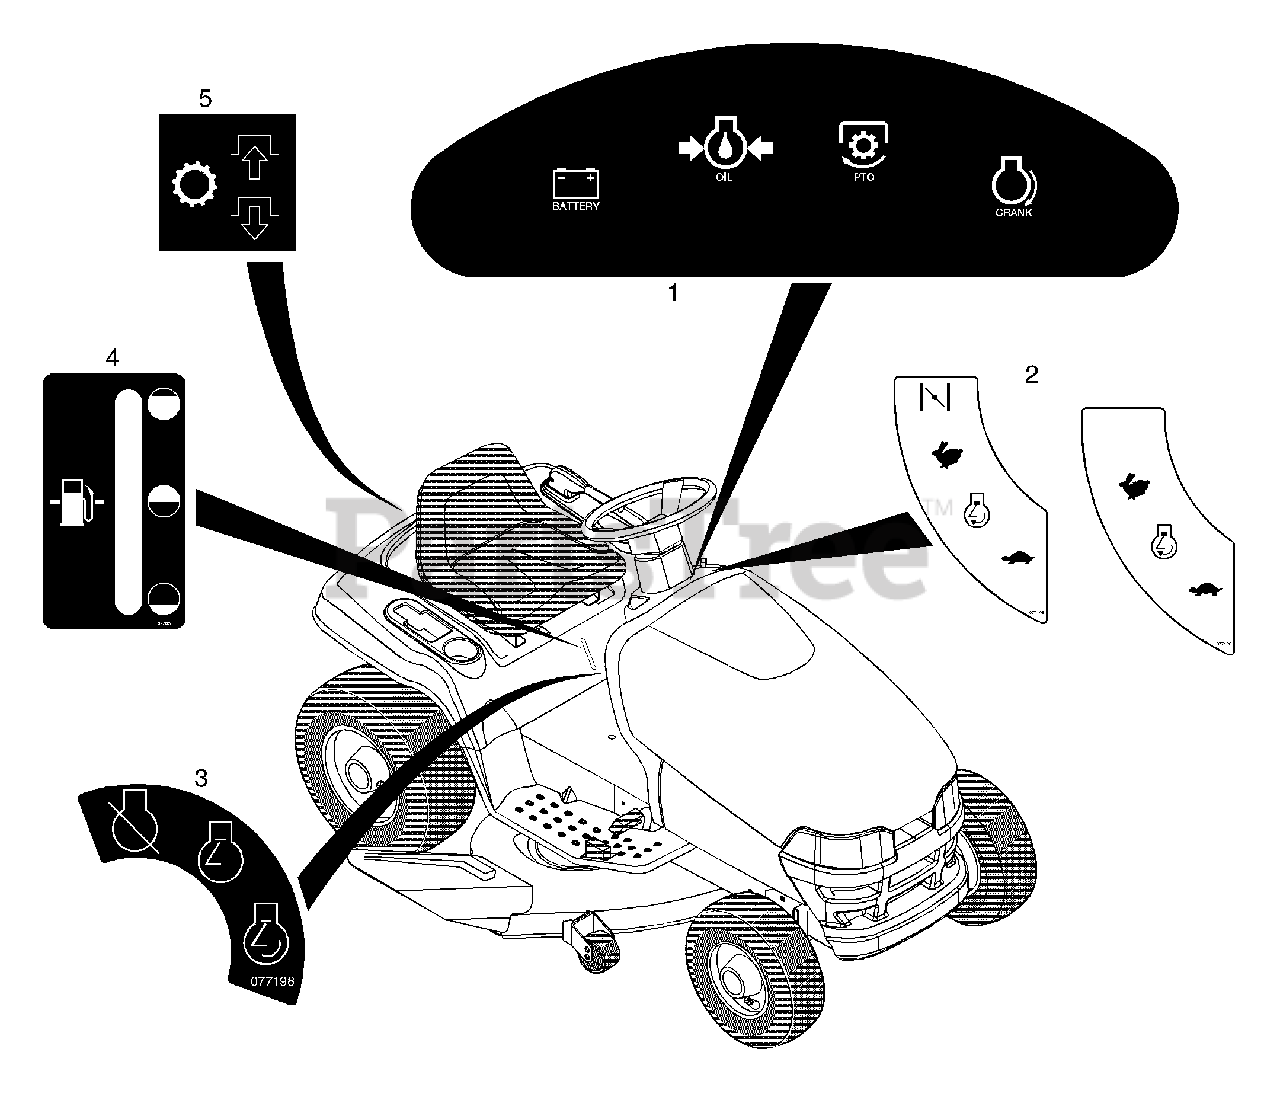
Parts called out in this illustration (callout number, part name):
1	DECAL - DASH W/LIGHTS
2	DECAL- THROTTLE W/ CHOKE
3	DECAL - IGNITION
4	DECAL- FUEL LEVEL
5	DECAL-TRANS. DISCONNECT
